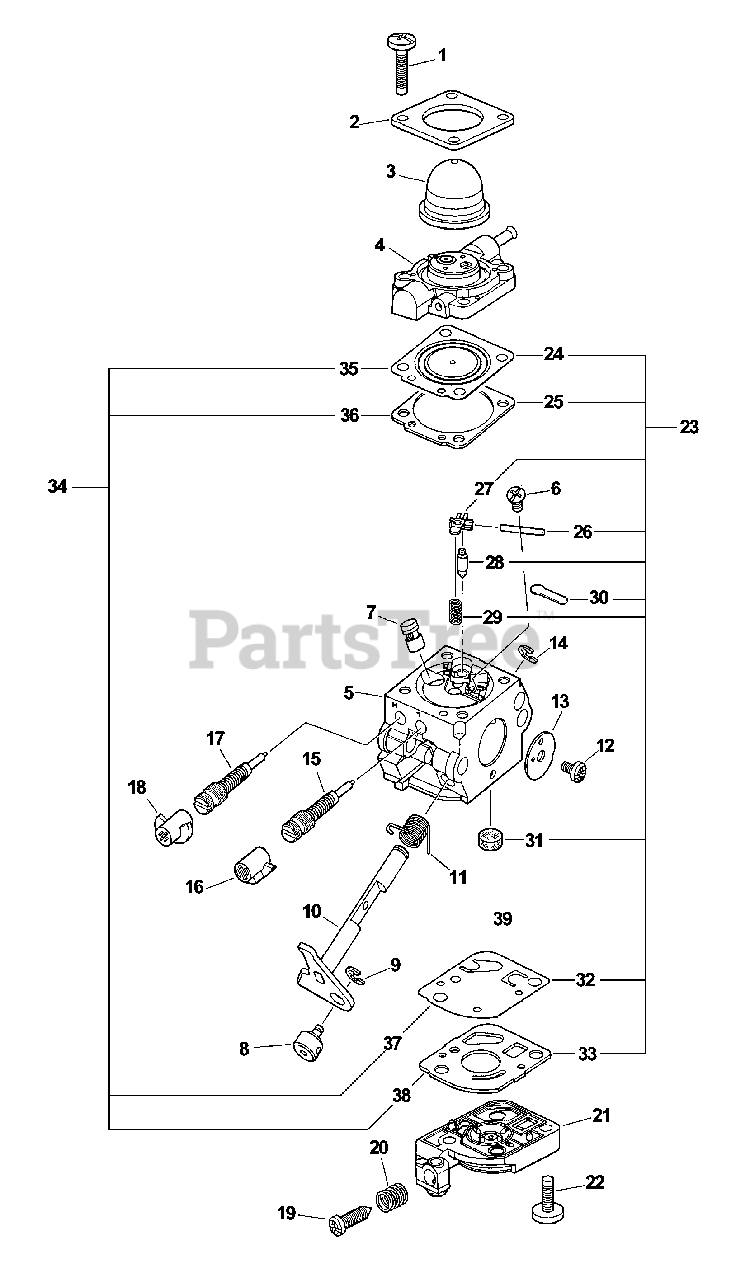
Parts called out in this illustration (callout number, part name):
1	SCREW, RETAINER
2	RETAINER, PURGE BULB
3	BULB, PURGE
4	BASE, PURGE
5	BODY, CARBURETOR
6	SCREW, METERING LEVER PIN
7	NOZZLE, CHECK VALVE
9	RING, RETAINING
10	SHAFT, THROTTLE
11	SPRING, RETURN
13	VALVE, THROTTLE
14	RING, RETAINING
15	NEEDLE - LOW SPEED
16	CAP, LIMITER
17	NEEDLE - HIGH SPEED
18	CAP, LIMITER
19	SCREW, IDLE ADJUST
20	SPRING, IDLE ADJUST
21	BASE, PURGE
22	SCREW, PUMP COVER
23	REPAIR KIT
24	DIAPHRAGM, METERING
25	GASKET, METERING
26	PIN, METERING LEVER
27	LEVER, METERING
28	VALVE, INLET NEEDLE
29	SPRING, METERING LEVER
30	PLUG, WELCH
31	STRAINER
32	DIAPHRAGM, PUMP
33	GASKET, PUMP
34	DIAPHRAGM/GASKET KIT
35	DIAPHRAGM, METERING
36	GASKET, METERING
37	DIAPHRAGM, PUMP
38	GASKET, PUMP
